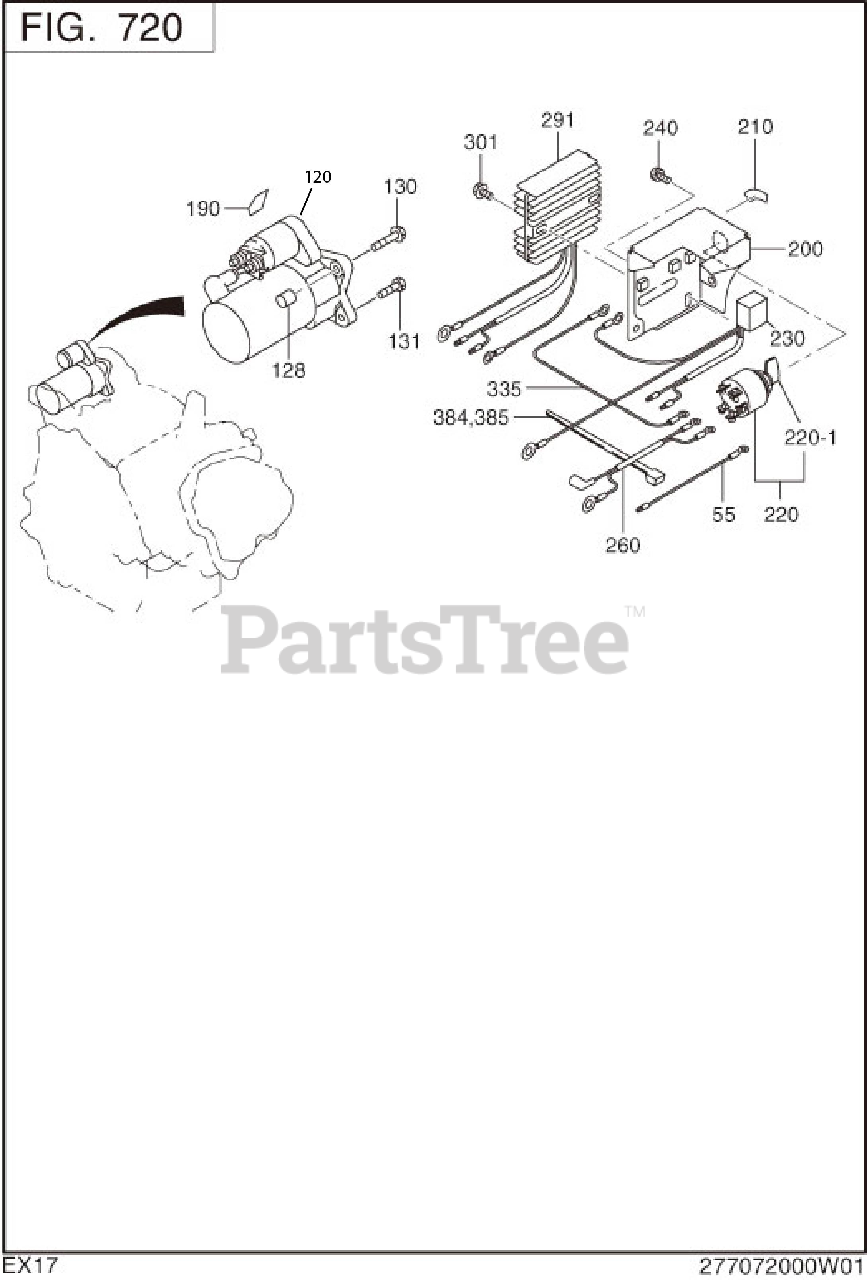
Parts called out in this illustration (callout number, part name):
190	LABEL(BATTERY)
200	CONTROL BOX CP
210	LABEL(STARTER SWITCH
220	SWITCH
230	DIODE RECTIFIER CP
240	SCREW AND WASHER AY
